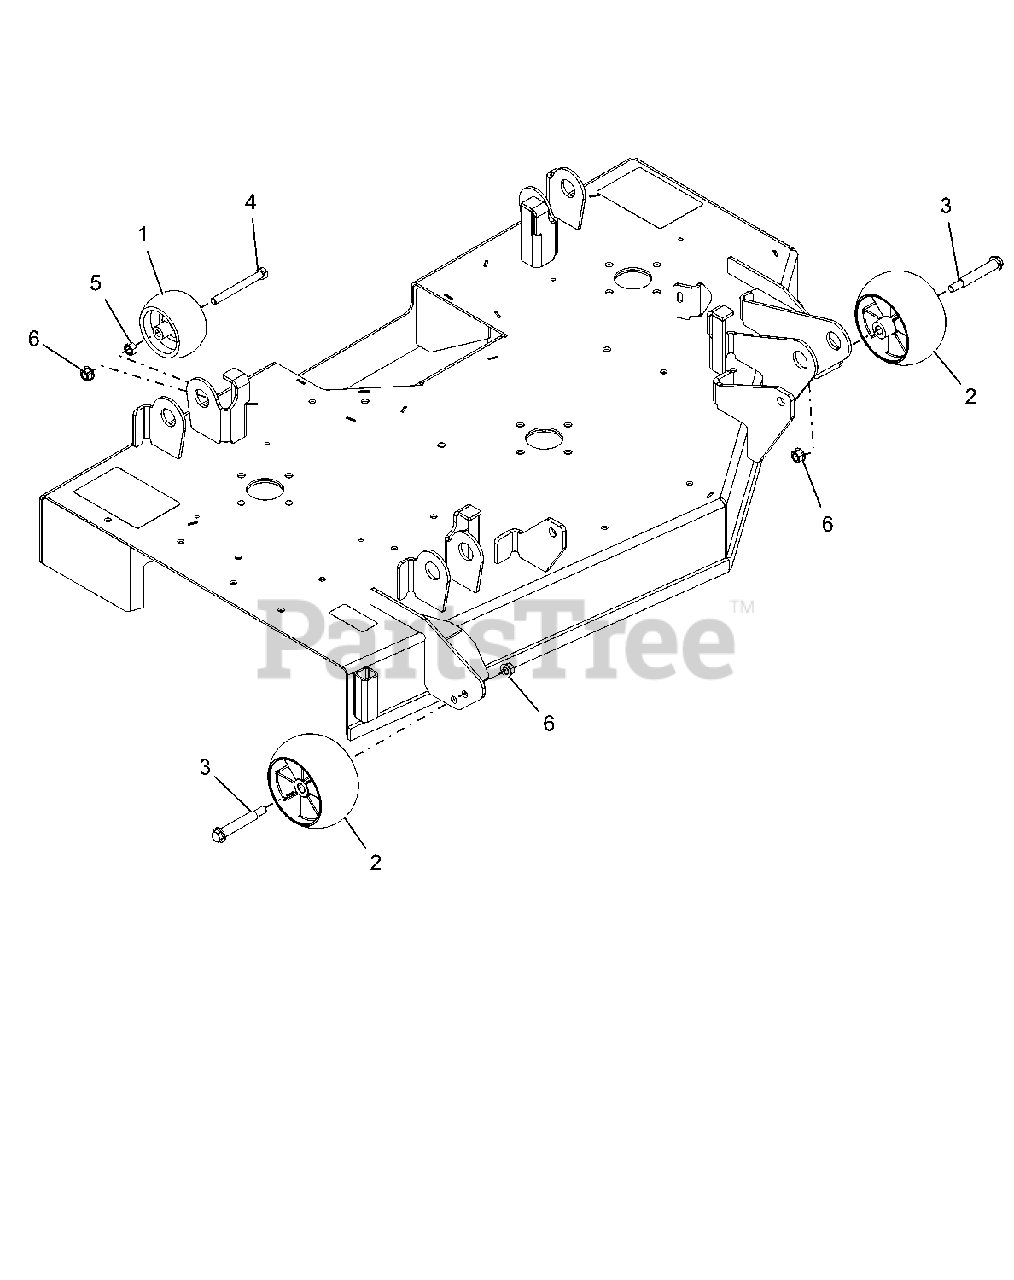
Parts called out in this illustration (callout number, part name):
2	ANTI-SCALP WHEEL - 5X OS
3	BLT-SHLDR .38-16X2.50 HWH G5
4	@BLT-HEX .38-16X3.50 GR5 YWZC
5	@NUT-HEX .38-16 YWZC
6	@NUT-LK-TOP-FLG .38-16 YWZC
